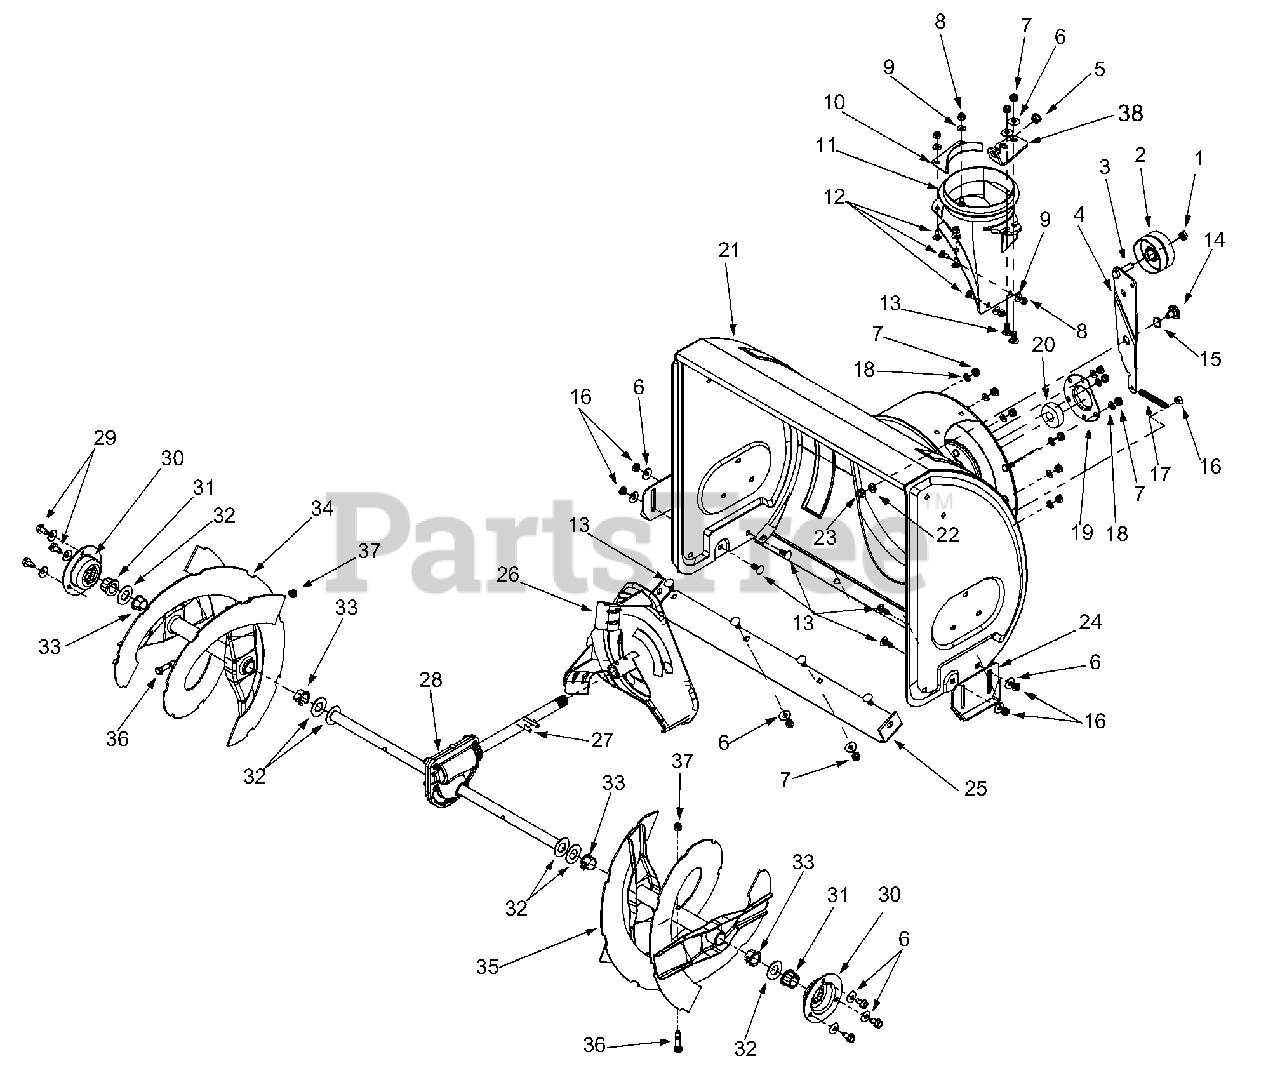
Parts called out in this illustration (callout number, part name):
1	Lock Jam Nut 3/8-24
2	Flat Idler
4	Hex Cap Screw 3/8-24 x 1.50
5	Bushing
6	Bell Washer
7	Hex Nut 5/16-18
8	Hex Lock Nut 1/4-20
9	Flat Washer
11	Chute Adapter
12	Carriage Screw 1/4-20 x .62
13	Carriage Bolt 5/16-18
14	Shoulder Screw
15	Wave Washer
16	Hex Nut 5/16-18
17	Extension Spring
18	Lock Washer 5/16
19	Bearing Housing
20	Ball Bearing
23	Hex Nut 3/8-16
28	24" Gear Assembly
29	Hex Washer Screw 5/16-18
31	Hex Flange Bearing
32	Flat Washer
33	Flange Bushing
37	Lock Nut 5/16-18
